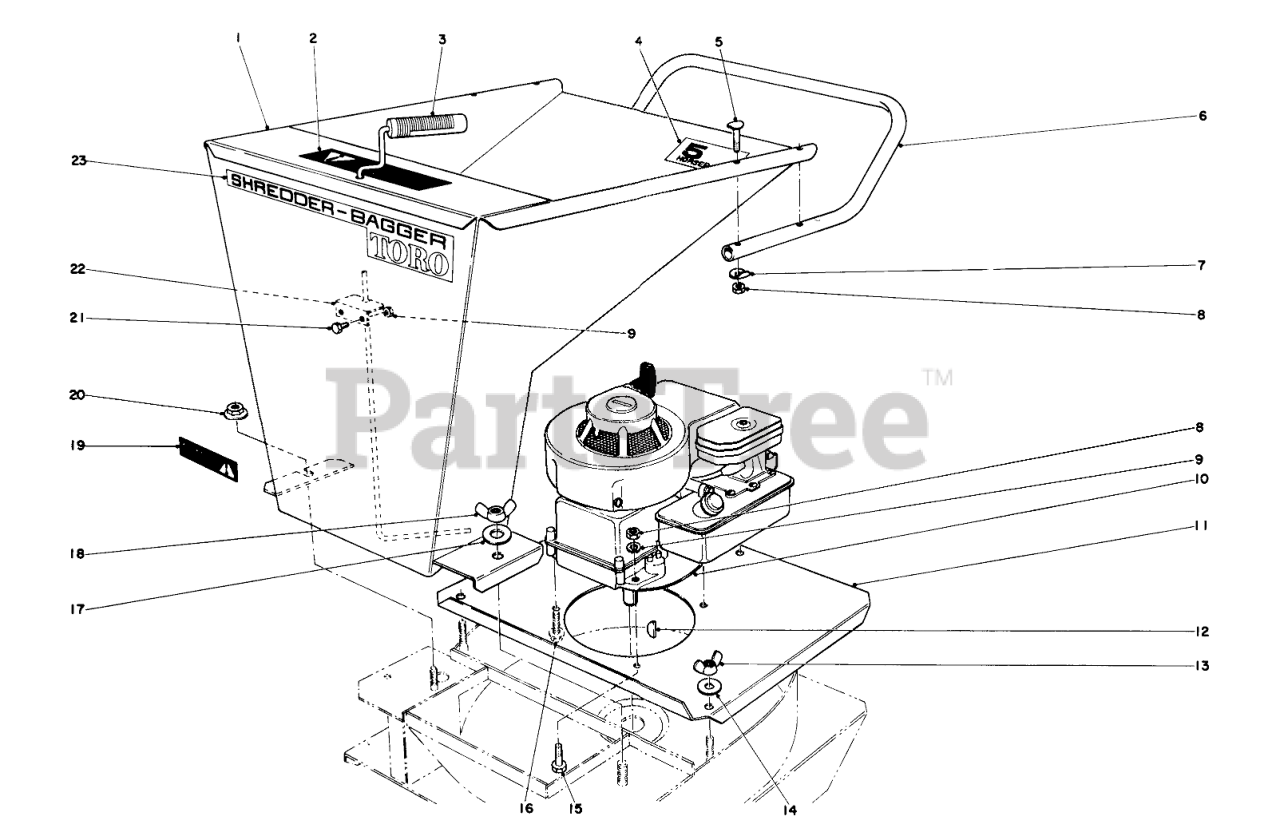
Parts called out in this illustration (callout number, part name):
1	Hopper
2	Caution Decal
3	Feeder rod
4	Decal, 5 HP
5	HANDLE SCREW
6	Handle
7	WASHER
8	NUT-HEX
9	WASHER-LOCK
10	Engine, 5 HP
11	Engine base plate
13	Wing nut
14	WASHER-FLAT
16	SCREW-HWHTF
17	WASHER-FLAT
18	Wing nut
19	Decal-warning
20	FLANGE NUT W/LG FLG
21	SCREW-HH
22	Clip-rod
23	Decal,logo
